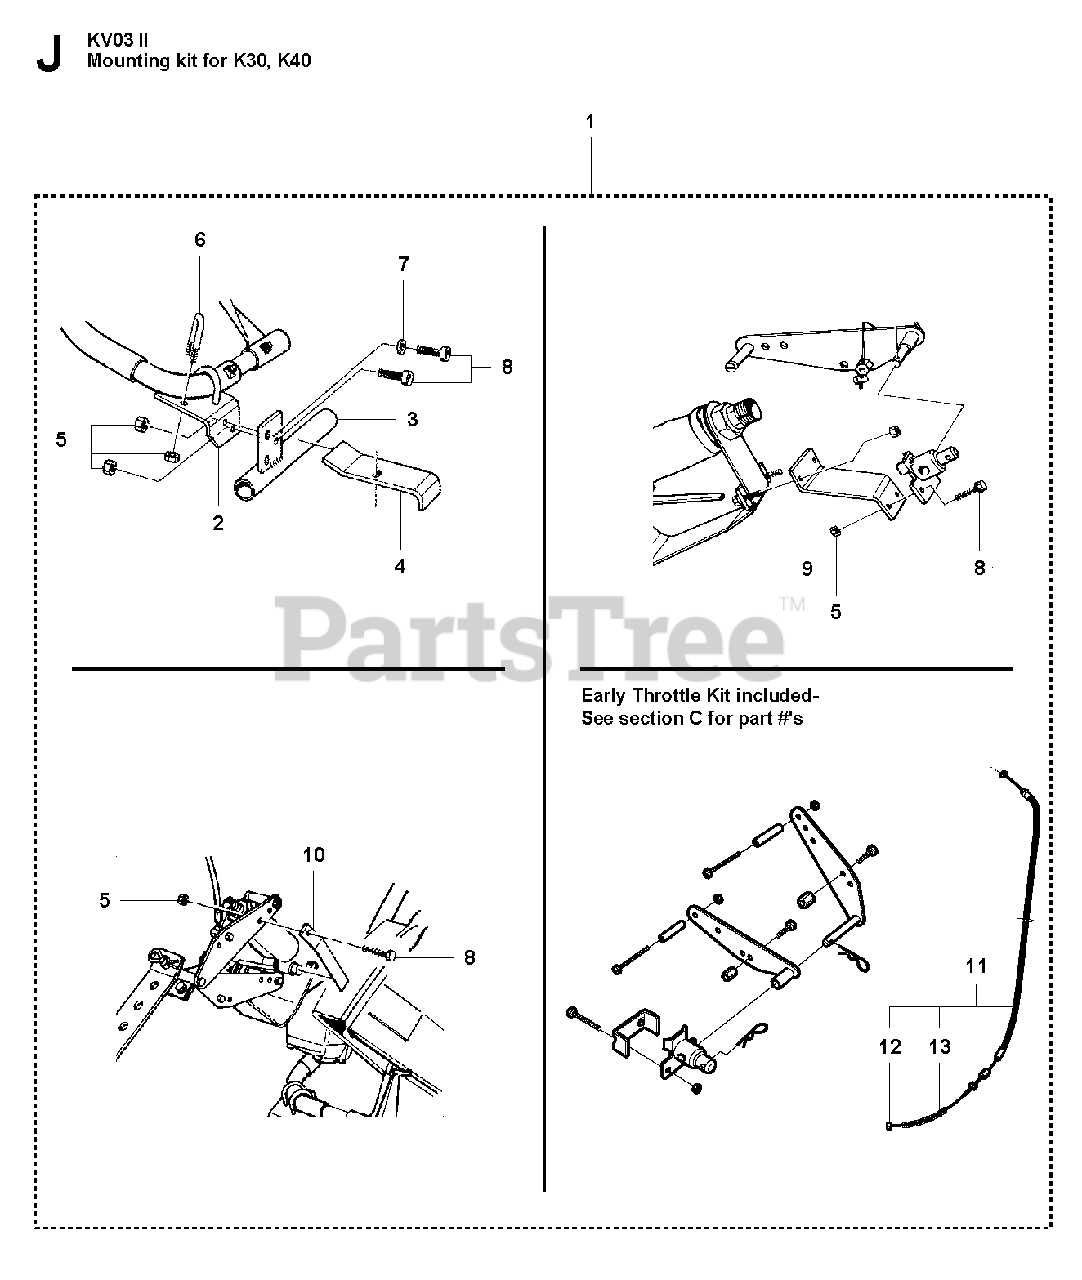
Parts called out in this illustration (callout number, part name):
1	CUTTING TROLLEYIncl. 2 - 11
4	PRESSURE PLATE
11	THROTTLE WIREIncl. 12, 13
